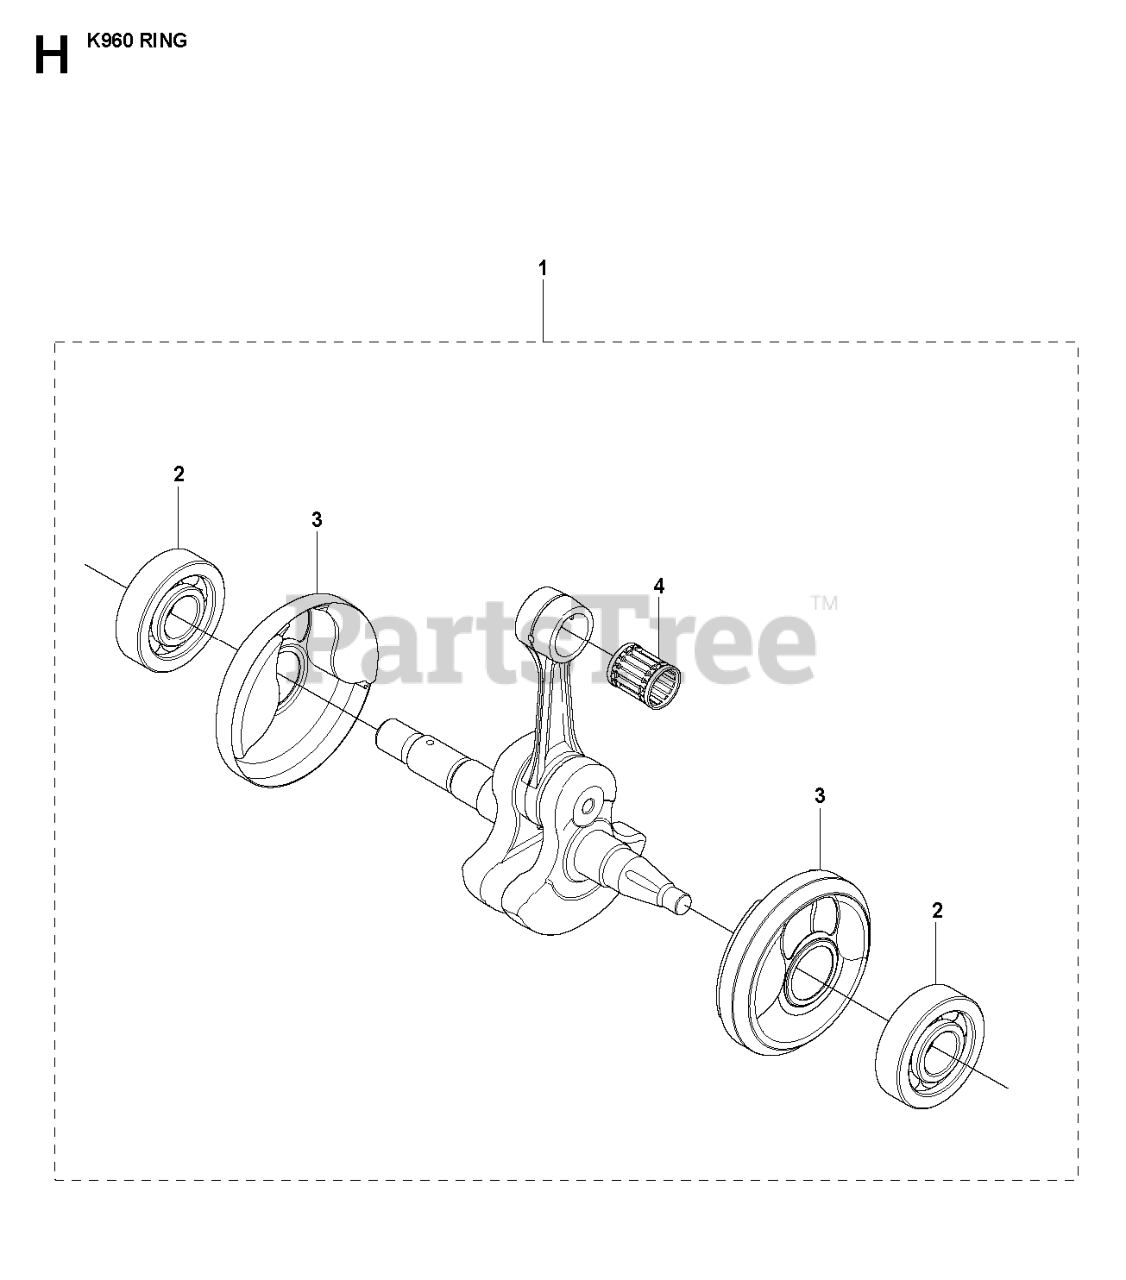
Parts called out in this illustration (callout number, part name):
1	CRANKSHAFT ASSY
2	BALL BEARING 6203C3QE6
4	SUPPORT BUSHING
